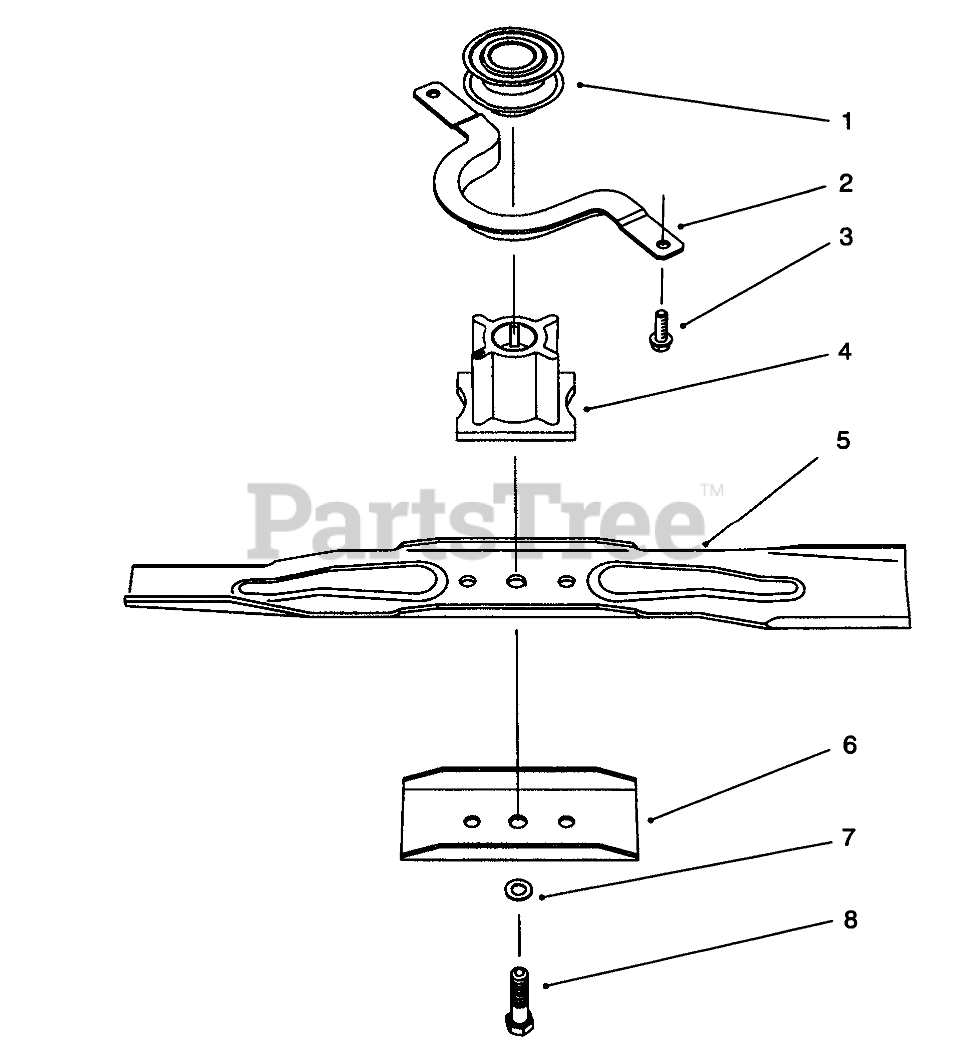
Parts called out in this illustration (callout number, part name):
1	PULLEY-DRIVE, ZONE START
2	Guide-Belt
3	SCREW-HWH
4	BLADE RETAINER - 25 MM
5	Blade
6	Stiffener Blade
7	WASHER-LOCK
8	BOLT-BLADE
